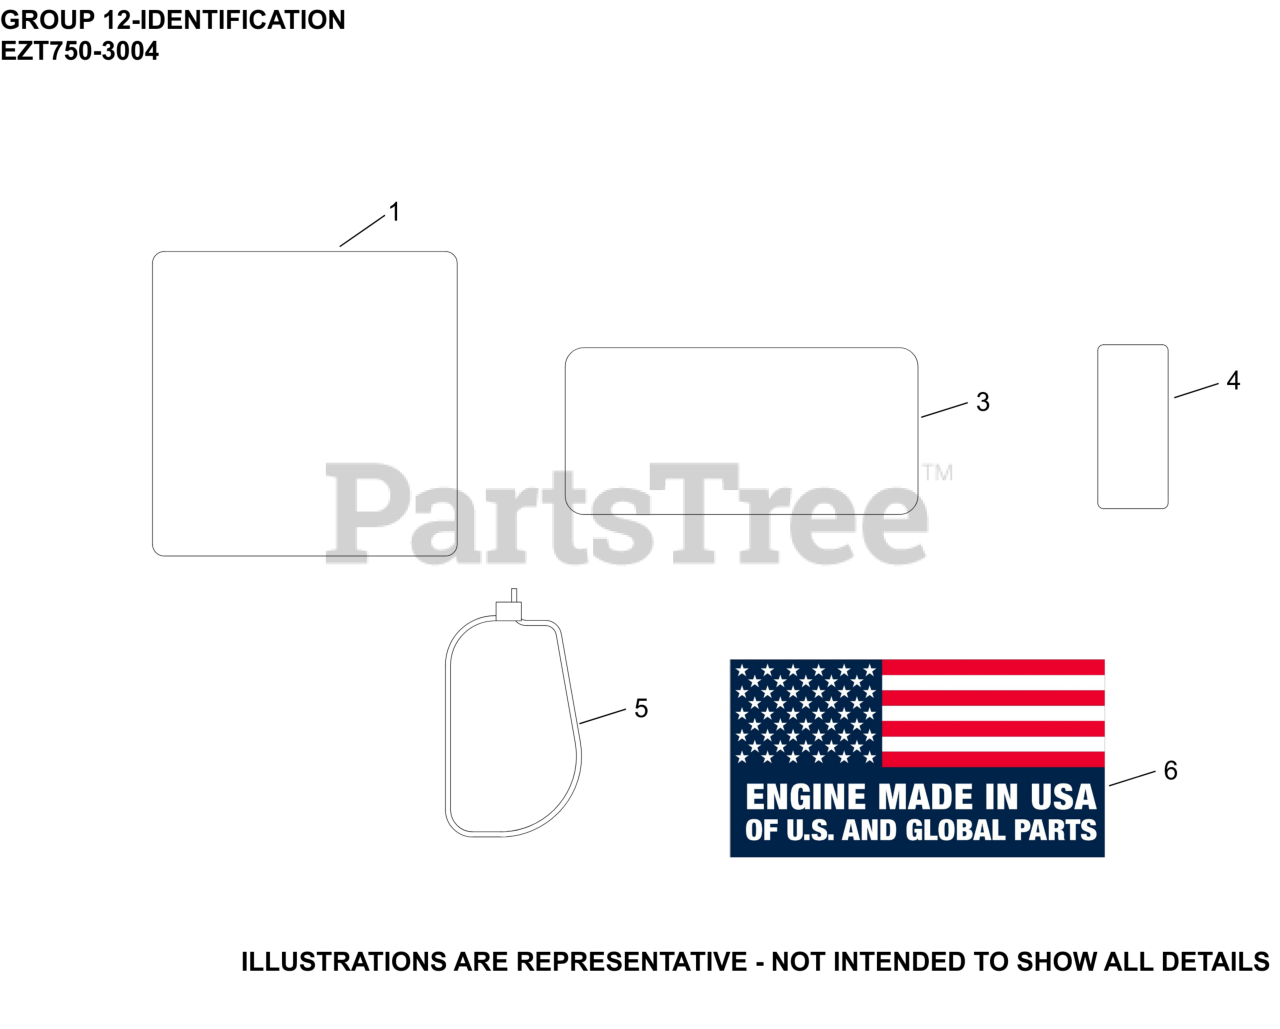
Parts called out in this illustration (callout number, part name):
1	LABEL, CONFIDANT (EZT750, 27HP)
3	LABEL, CANADIAN COMPLIANCE
4	LABEL, CLEAR LAMINATION
6	DECAL, USA
